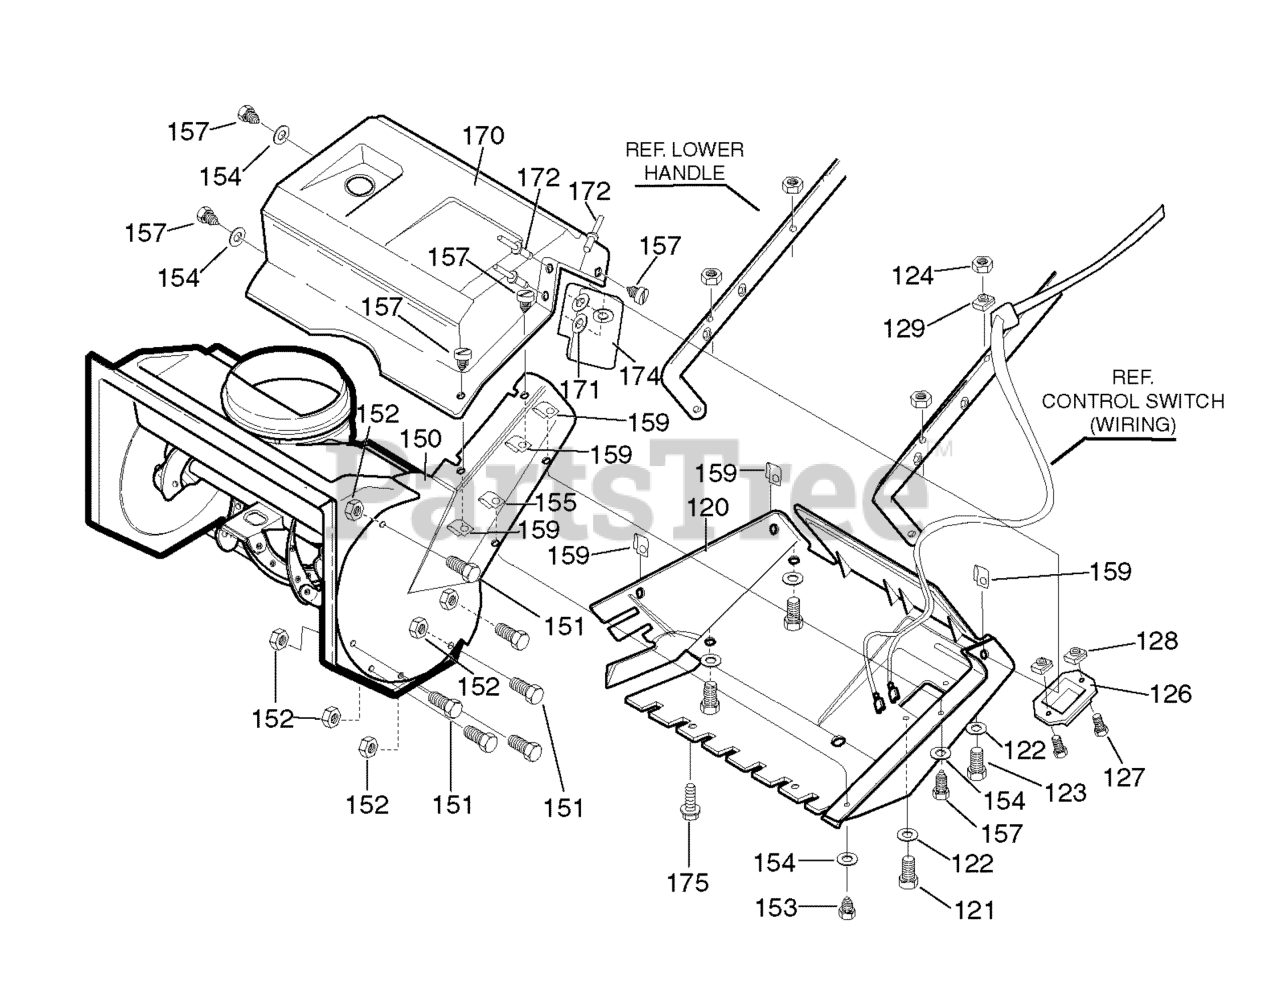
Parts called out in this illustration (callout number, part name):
120	BOTTOM COVER
121	SCREW, 1/4-20 x 1.25
122	FLATWASHER
123	SCREW, 1/4-20 x 1.50
124	NUT, 1/4-20
126	CABRURATOR COVER
127	SCREW, 1/4-14 x .75
128	NUT, 1/4-10
129	CABLE CLIP
150	COVER, BELT
151	SCREW, 10-24 x .50
152	NUT, #10-24
153	SCREW, 1/4-20 x .50
154	FLATWASHER
155	NUT, 1/4-20
157	SCREW, 1/4-14 x .75
159	NUT, 1/4-10
170	TOP COVER
171	FLATWASHER
174	SIDE COVER
175	SCREW 10-14 x 0.63
